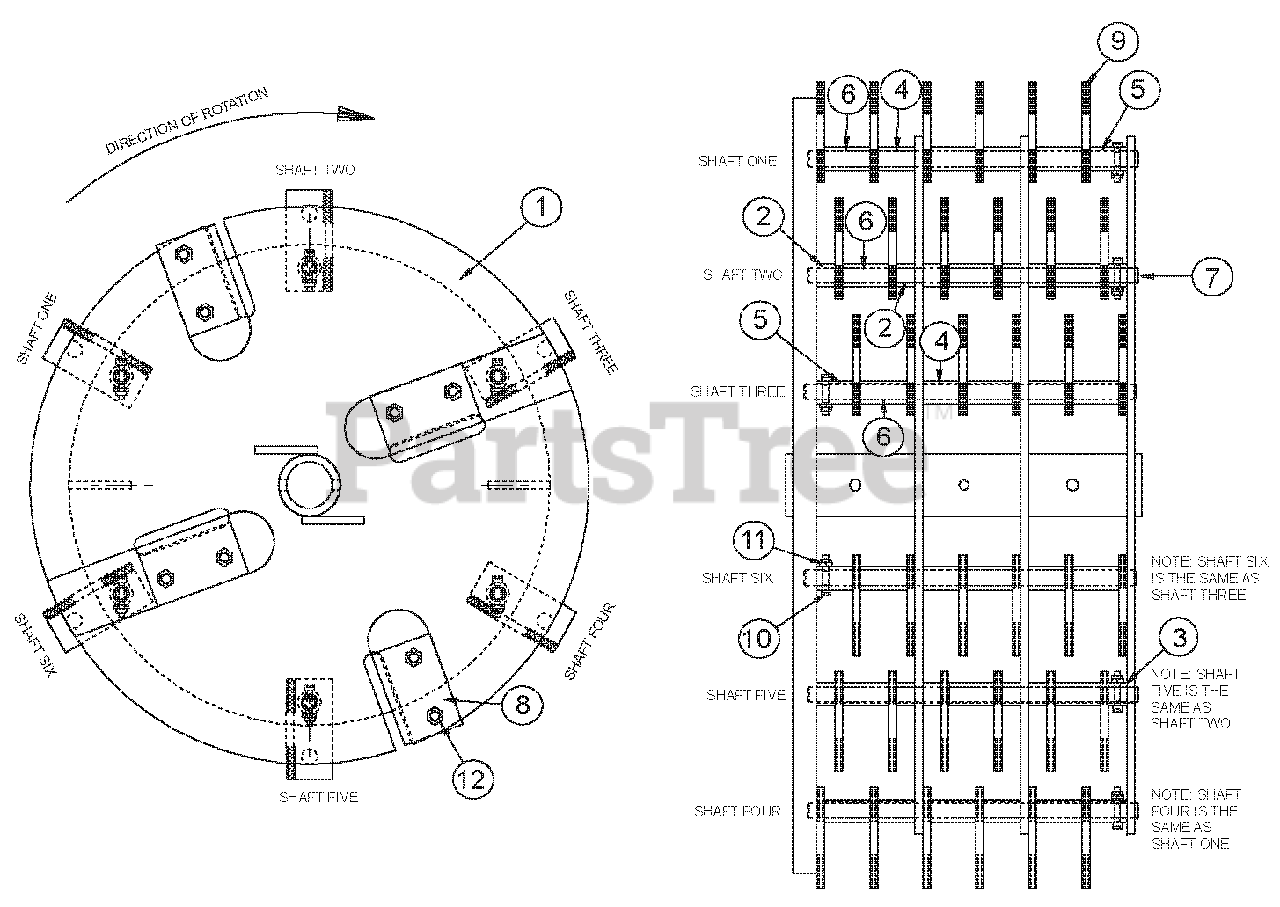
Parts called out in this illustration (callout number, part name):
1	WELDMENT, LARGE ROTOR
2	SPACER, .75 X .59
3	SPACER, .75 X .59 W/HOLE
4	SPACER, .75 X 1.18
5	SPACER, .75 X 1.18 W/HOLE
6	SPACER .75 X 1.47
7	SHAFT, COMM. KNIFE
8	BLADE, TOOL STEEL CHIPPER
9	KNIFE, RECT. SHREDDER
10	BOLT, 10-24 X 1-1/8 SKT
11	NUT, 10-24 NYLOCK
12	BOLT, 5/16 X 1 HEX HD
